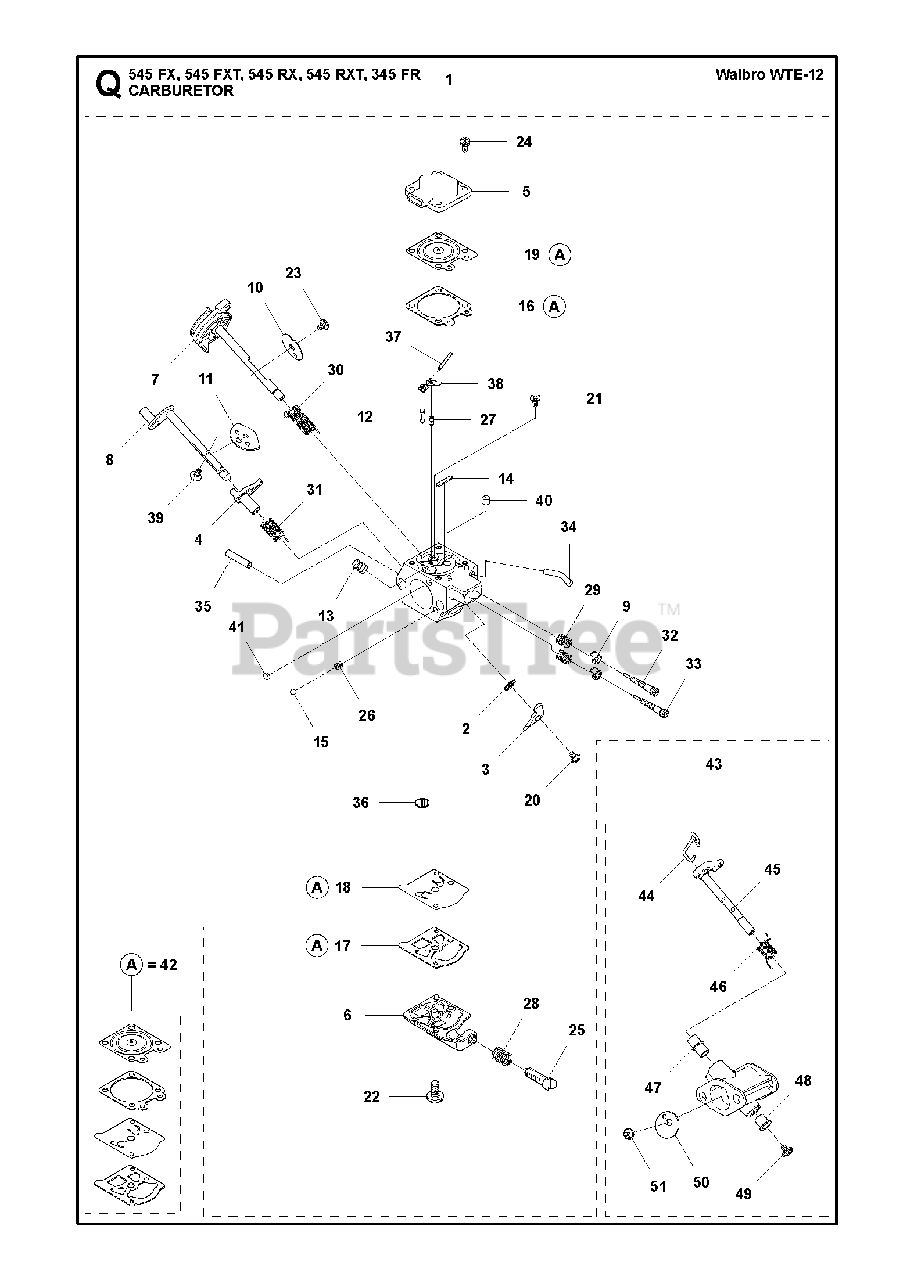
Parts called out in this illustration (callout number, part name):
1	CARBURETOR
2	CLIP
3	LEVER
4	LEVER
5	COVER
6	COVER
7	SHAFT ASSY
8	SHAFT
9	LIMITER CAP
10	THROTTLE FLAP
11	VALVE
12	INLET NEEDLE
13	NOZZLE ASSY
14	PLUG
15	BALL
16	GASKET
17	GASKET
18	DIAPHRAGM
19	DIAPHRAGM
20	SCREW
21	SCREW
22	SCREW
23	SCREW
24	SCREW
25	SCREW
26	SPRING
27	SPRING
28	SPRING
29	SPRING
30	SPRING
31	SPRING
32	NEEDLE
33	NEEDLE
34	FITTING
36	FUEL INLET SCREEN
37	FULCRUM PIN
38	LEVER
39	SCREW
40	JET
41	PLUG WELCH
44	LINK
45	SHAFT
46	SPRING
47	BUSHING
48	BUSHING
49	SCREW
50	VALVE
51	SCREW
